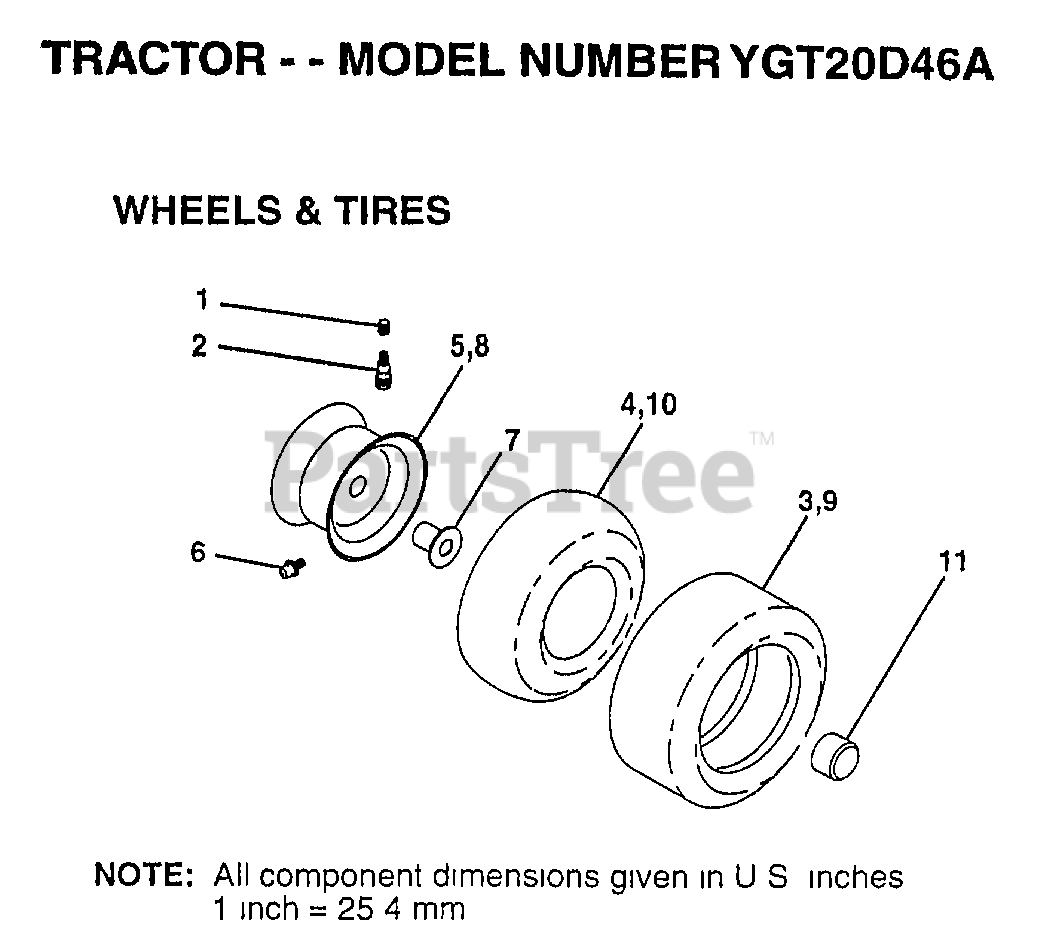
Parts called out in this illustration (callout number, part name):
1	VALVE CAP
2	VALVE STEM LT
4	TUBE.5.3/4.5/6
5	RIM.FRONT.
6	FITTING LT
7	"FLANGE, BEARING"
8	RIM.REAR.417
10	TUBE.23X8/10-12
11	HUB CAP
